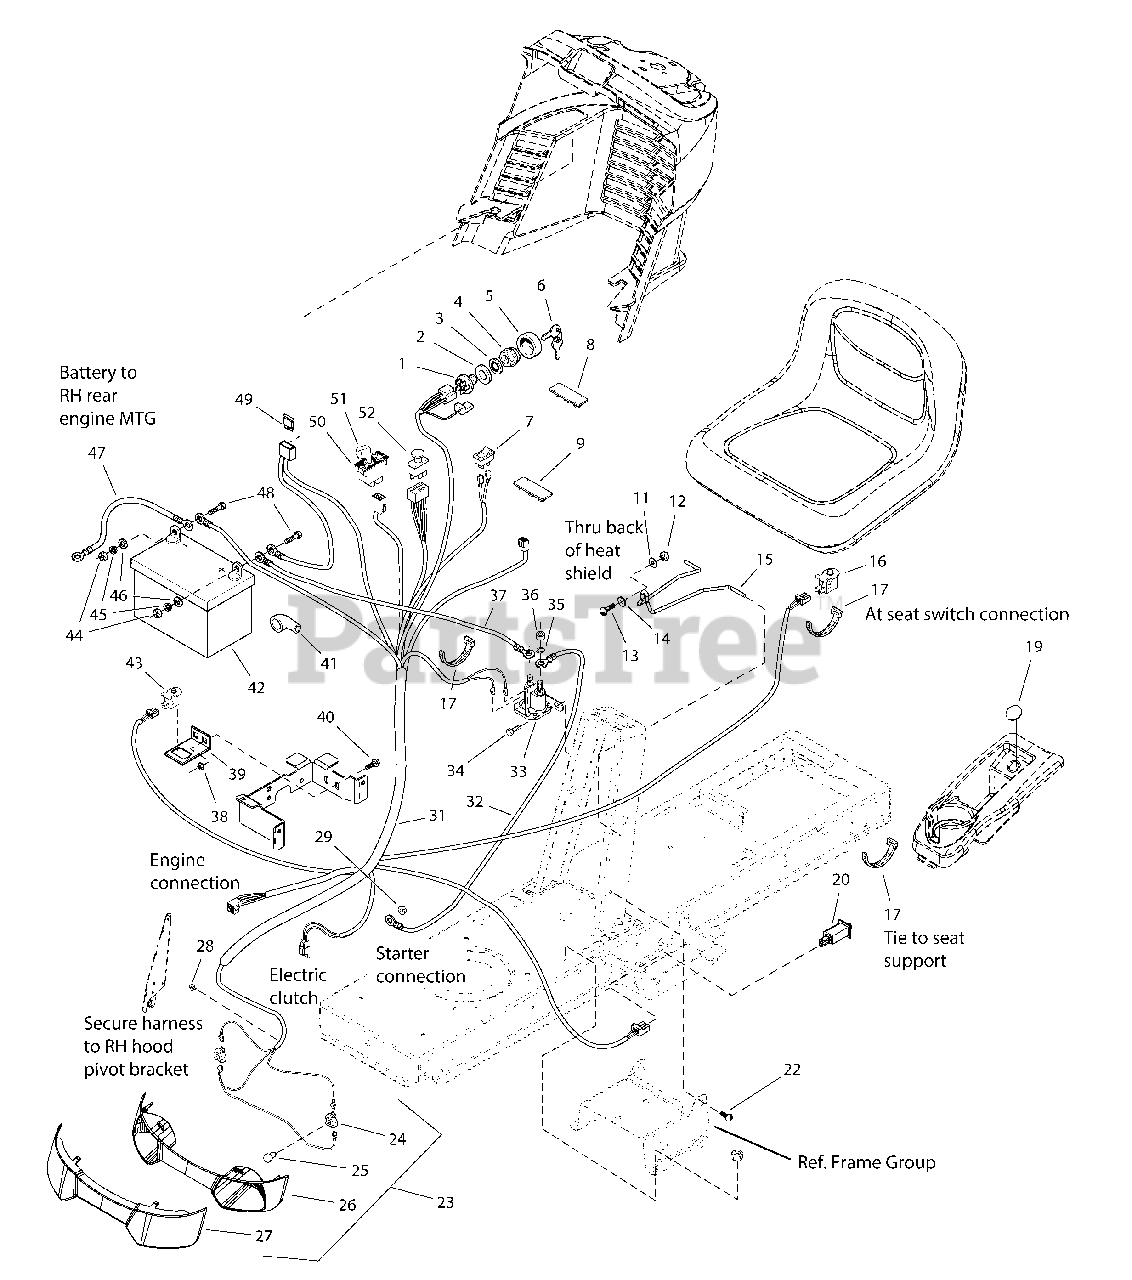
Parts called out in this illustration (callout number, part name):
1	SWITCH, Ignition, 6-Pole (Hdwe. Not Included)
2	WASHER, 5/8
3	LOCKWASHER, Internal Tooth, 5/8
4	NUT, Hex, Flange, 5/8-32
5	COVER, Ignition
6	IGNITION KEY (Set of 2)
7	SWITCH, Headlights, 2 Terminal
8	PLUG, Hole, Square
9	PLUG, Hour Meter
10	METER, Hour, LCD
11	WASHER, Plain, 1/4 (6 Total for Export)
12	NUT, Wing, 1/4-20
13	BOLT, Carriage, 1/4-20 x 7/8
14	NUT, Push On
15	HOLD DOWN, Battery
16	SWITCH, Push Button (NC)
17	TIE, Self Locking 7-5/16
18	OUTLET, 12 Volt DC Power
19	PLUG, Hole Models W/O 12V Adapter
20	SWITCH, Push Button (NO/NC)
21	SUPPORT, Battery 12 GA
22	SCREW, Taptite, 5/16-18 x 5/8
23	HEADLIGHT ASSEMBLY
24	SOCKET ASSEMBLY
25	BULB, 1141-12V 21CP
26	REFLECTOR, Headlight
27	LENS, Headlight
28	CLIP, Speed Wire
29	NUT, Hex, Flange, 1/4-20
30	COVER, Terminal
31	HARNESS, Wiring
32	CABLE, Solenoid to Starter
33	SOLENOID
34	SCREW, Taptite, 1/4-20 x 1/2
35	LOCKWASHER, External Tooth, 5/16
36	NUT, Hex, 5/16-24 NF
37	CABLE, #6 x 10 Long, with 2 Ring Terminals, Battery to Solenoid
38	NUT, Hex, Flange Whizlock, 5/16-18
39	SUPPORT, RMO Switch
40	BOLT, Carriage, 5/16-18 x 3/4
41	BOOT, Insulator
43	SWITCH, Push Button, NO, Black
44	NUT, Hex, Full, 1/4-20
45	LOCKWASHER, 1/4
46	WASHER, 1/4 I.D.
47	CABLE, Battery to Ground
48	CAPSCREW, Hex Head, 1/4-20 x 3/4
49	FUSE, Wiring Harness
50	SWITCH, RMO Module Only
51	KEY, w/Hang Tag for RMO Module
52	SWITCH, PTO, Push/Pull Symbols
